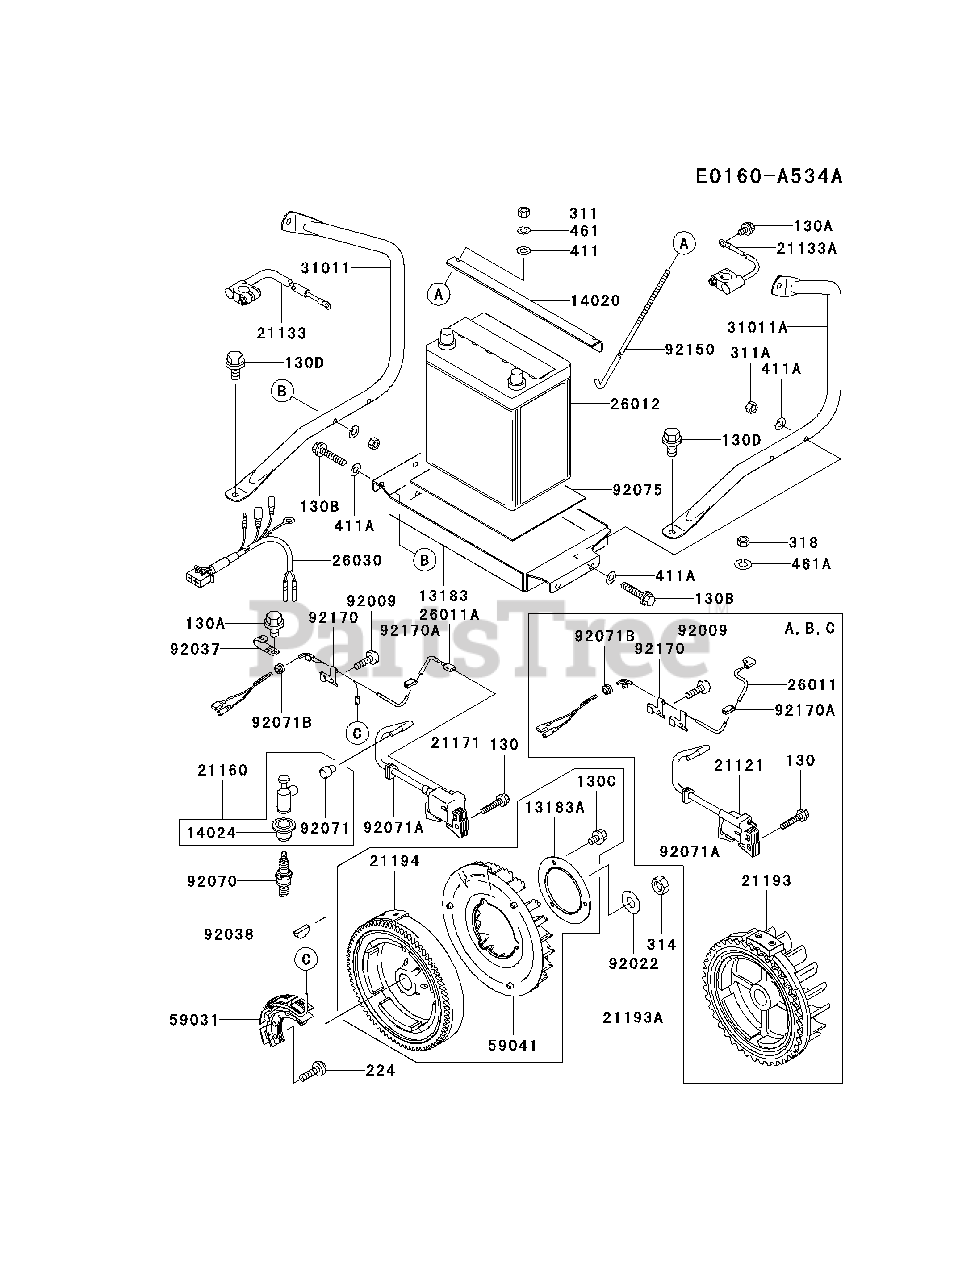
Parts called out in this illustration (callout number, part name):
314	NUT-HEX-FINE
318	NUT-HEX-SMALL
411	WASHER-PLAIN
411A	WASHER-PLAIN
461	WASHER-SPRING
461A	WASHER-SPRING
